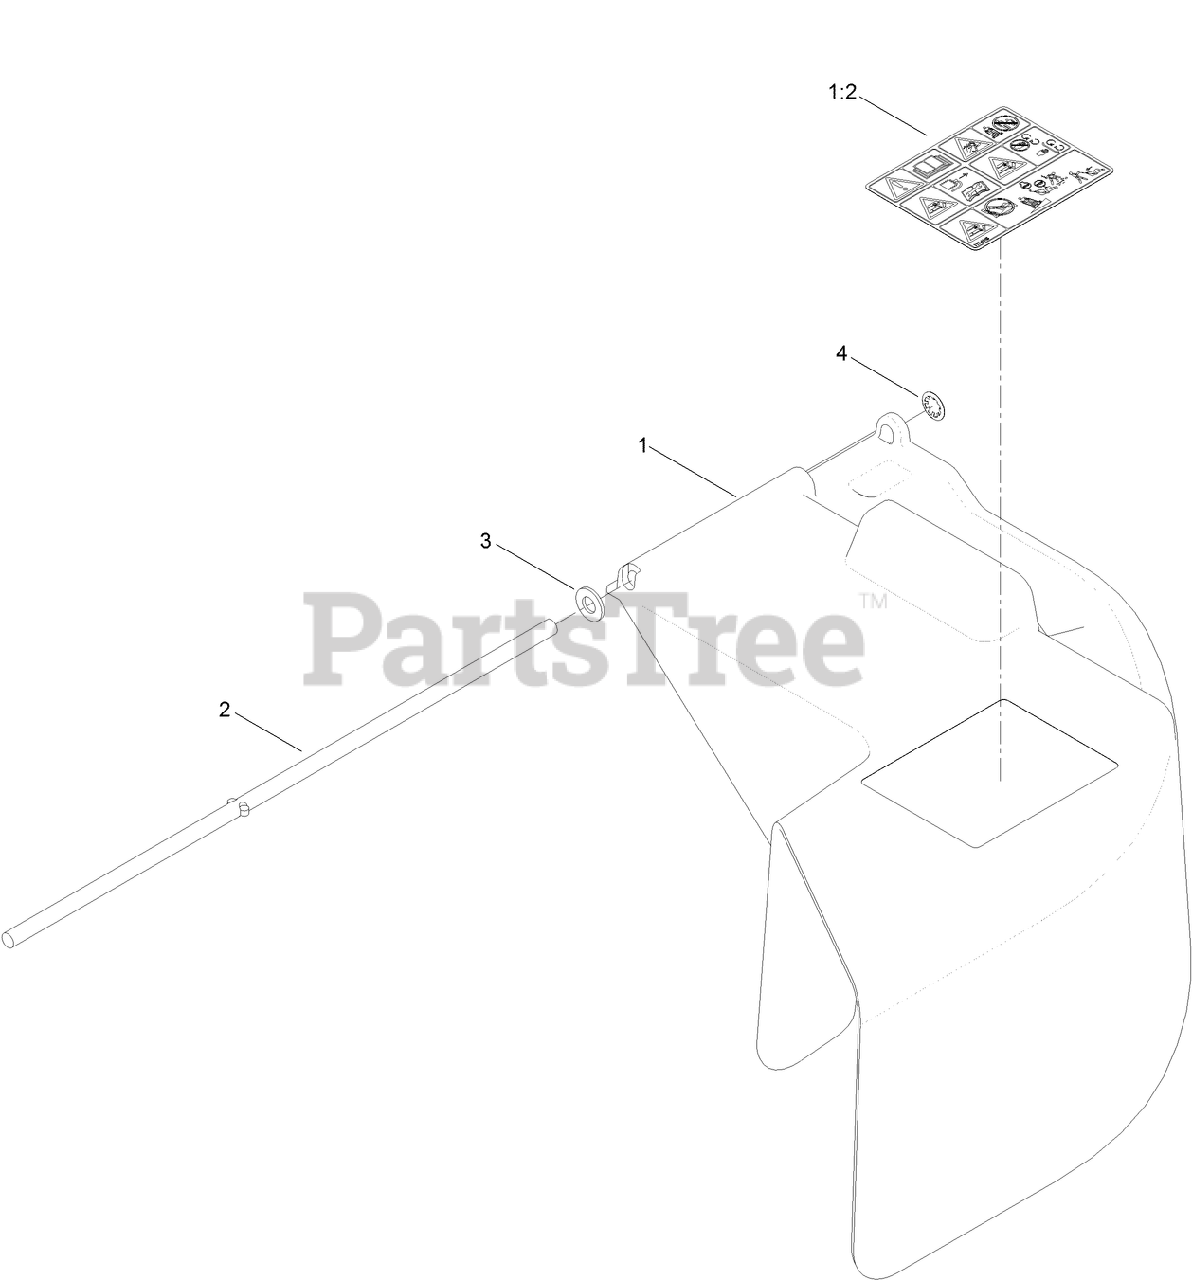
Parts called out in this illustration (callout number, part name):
1	DEFLECTOR-CHUTE
1:2	DECAL-WARNING
2	ROD
3	WASHER-PLAIN
4	RING-RETAINING
